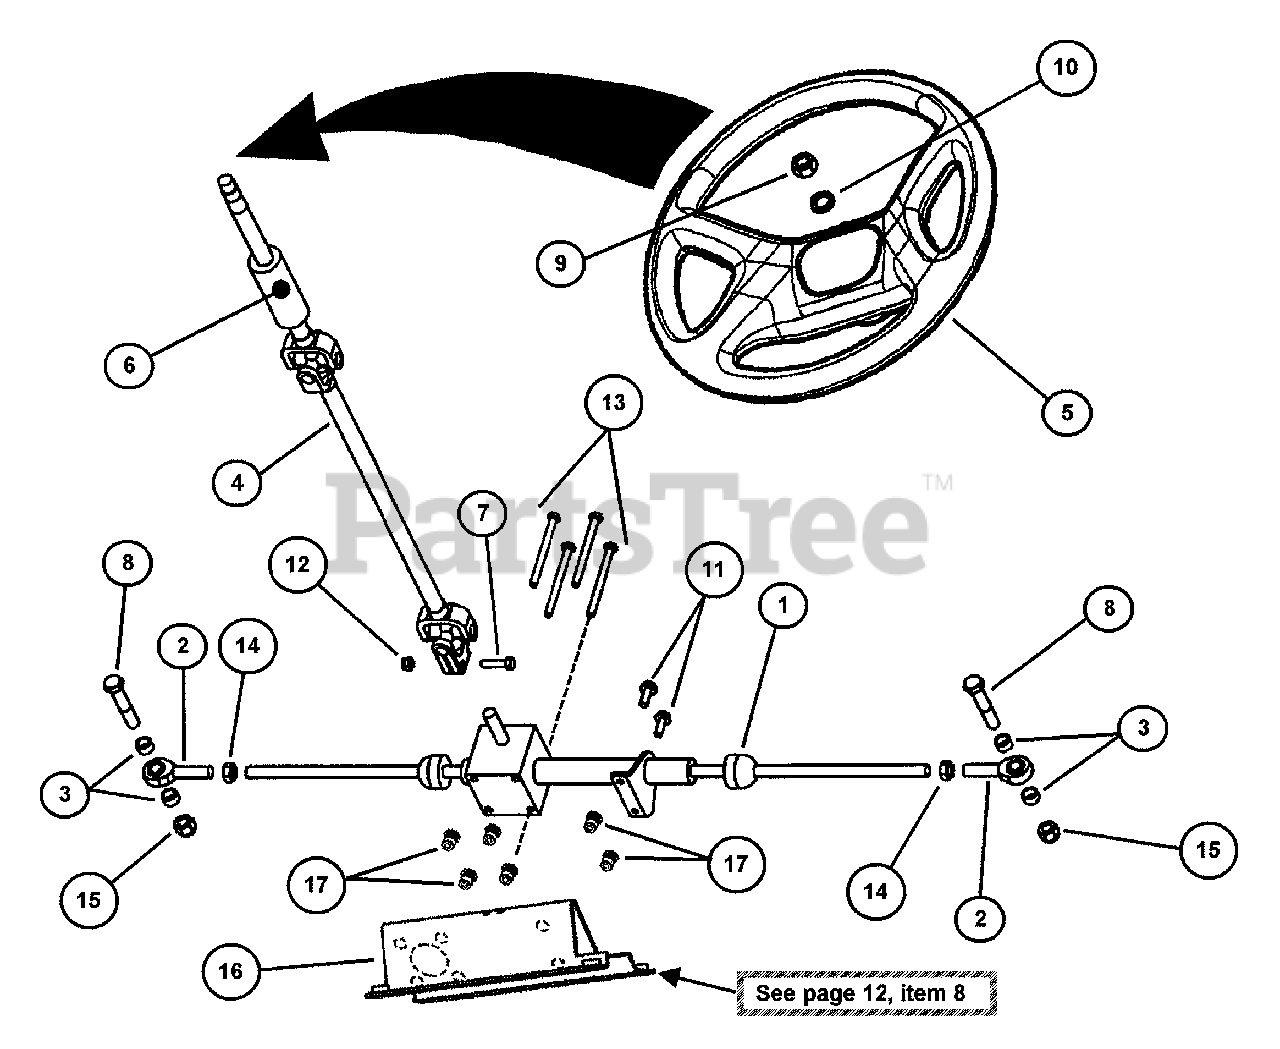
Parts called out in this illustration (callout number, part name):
1	RACK & PINION STEERING
2	BALL JOINT 1/2-20
3	SPACER, 1/2 ID, 5/8 OD X .375 YZ
4	STEERING COLUMN
5	STEERING WHEEL- SPLINED
6	COVER, STEERING SHAFT
7	HHCS, 5/16-18 X 1.25 GR 5 YZ
8	HHCS, 1/2-13 X 2-3/4 G R5
9	HN, M16 YZ
10	SLW, 16MM
11	HFLB, 5/16-18 X 7/8 YZ
12	HLN, 5/16-18-3B YZ ESNA
13	HHCS, 5/16C X 3-3/4
14	HJN, 1/2-20
15	HNYL, 1/2-13 YZ
16	WELDMENT, STEERING BRACKET
17	RIV-NUT, 5/16-18 Round
